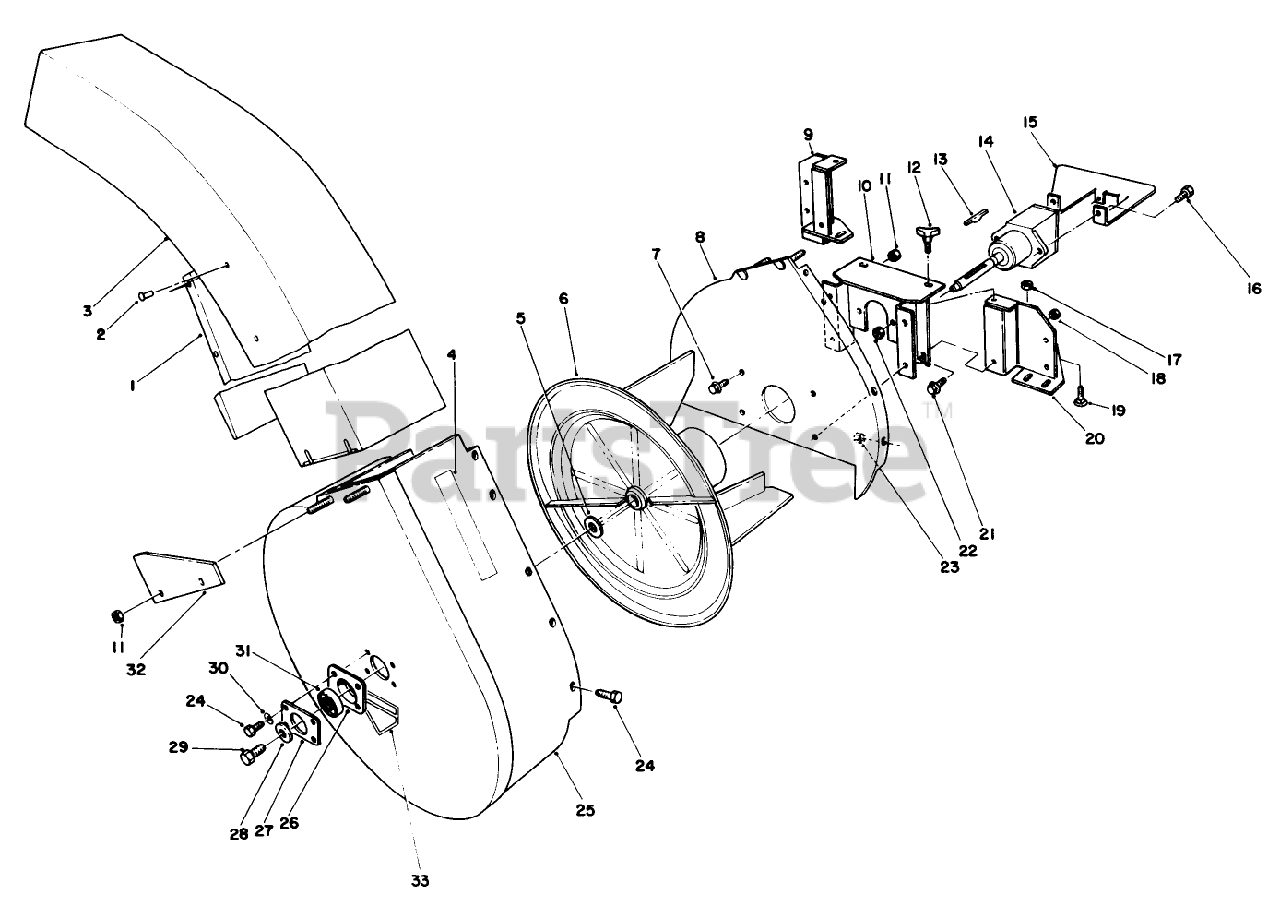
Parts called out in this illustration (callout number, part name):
1	Deflector
3	Chute Assembly (Incl. Ref. #1 & 2)
4	Decal-Waming
5	SPACER-BEARING
6	Impeller
7	SCREW-HHF
8	Mounting Plate
9	L/H BLOWER MT/NUT ASM
10	Blower Mount
11	NUT-LOCK, NI
14	Asm-Gear Box
15	Cover-Gear Box
16	SCREW-HH
17	NUT-KEPS
18	NUT-JAM
19	SCREW-CARR
20	RH BLWR MT BRKT WA
21	SCREW-HHF
22	NUT-LOCK, NI
23	NUT-LOCK, NI
24	SCREW-HH
25	BLOWER HOUSING ASM
26	CUP-BEARING
27	Cover-Plate
28	SPACER
29	SCREW-HH, LOCK
30	WASHER-LOCK
31	BEARING-BALL
32	Bracket
33	DECAL-DANGER
